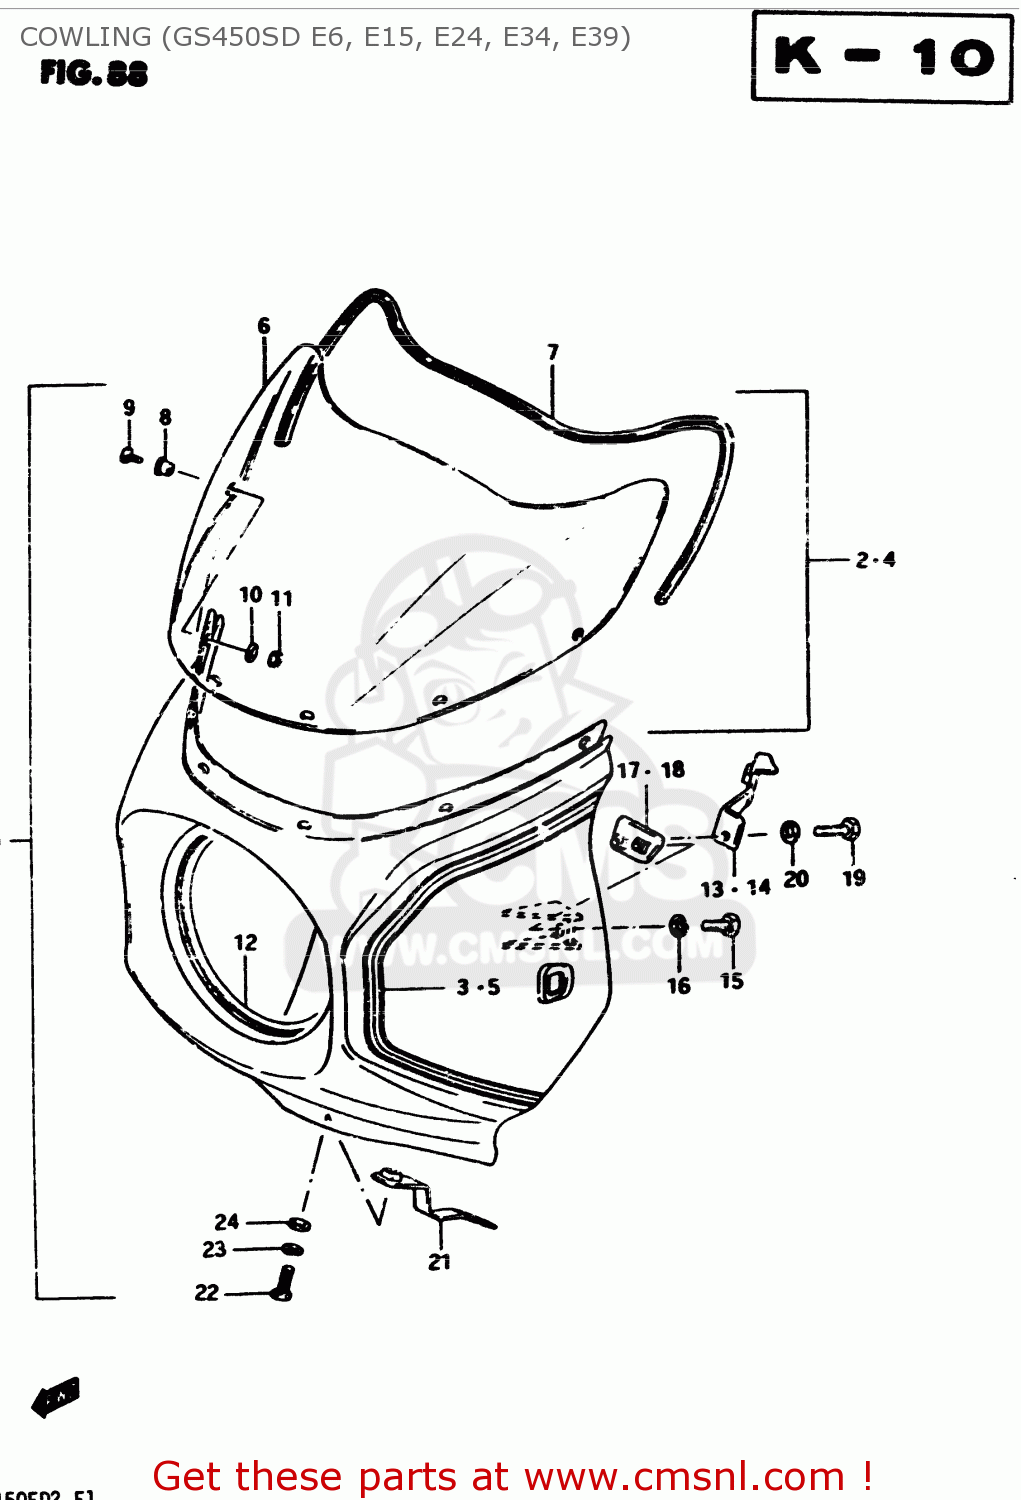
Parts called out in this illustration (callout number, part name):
1	COWLING ASSY (RED/BLACK)
2	COWLING ASSY
3	TAPE SET
4	COWLING ASSY
5	TAPE SET
6	WINDOW
7	MOULDING
8	CUSHION
9	SCREW M5X12 DIN 7985/N
10	WASHER,5MM
11	NUT
12	MOLDING,HEADLAMP GRILL
13	BRACKET,COWLING RH
14	BRACKET,COWLING LH
15	BOLT
16	LOCK WASHER
17	BRACKET, FITTING RH
18	BRACKET, FITTING LH
19	BOLT, UPPER
20	WASHER (6.5X18X1.6)
21	BRACKET, LOWER
22	BOLT
23	LOCK WASHER
24	WASHER
